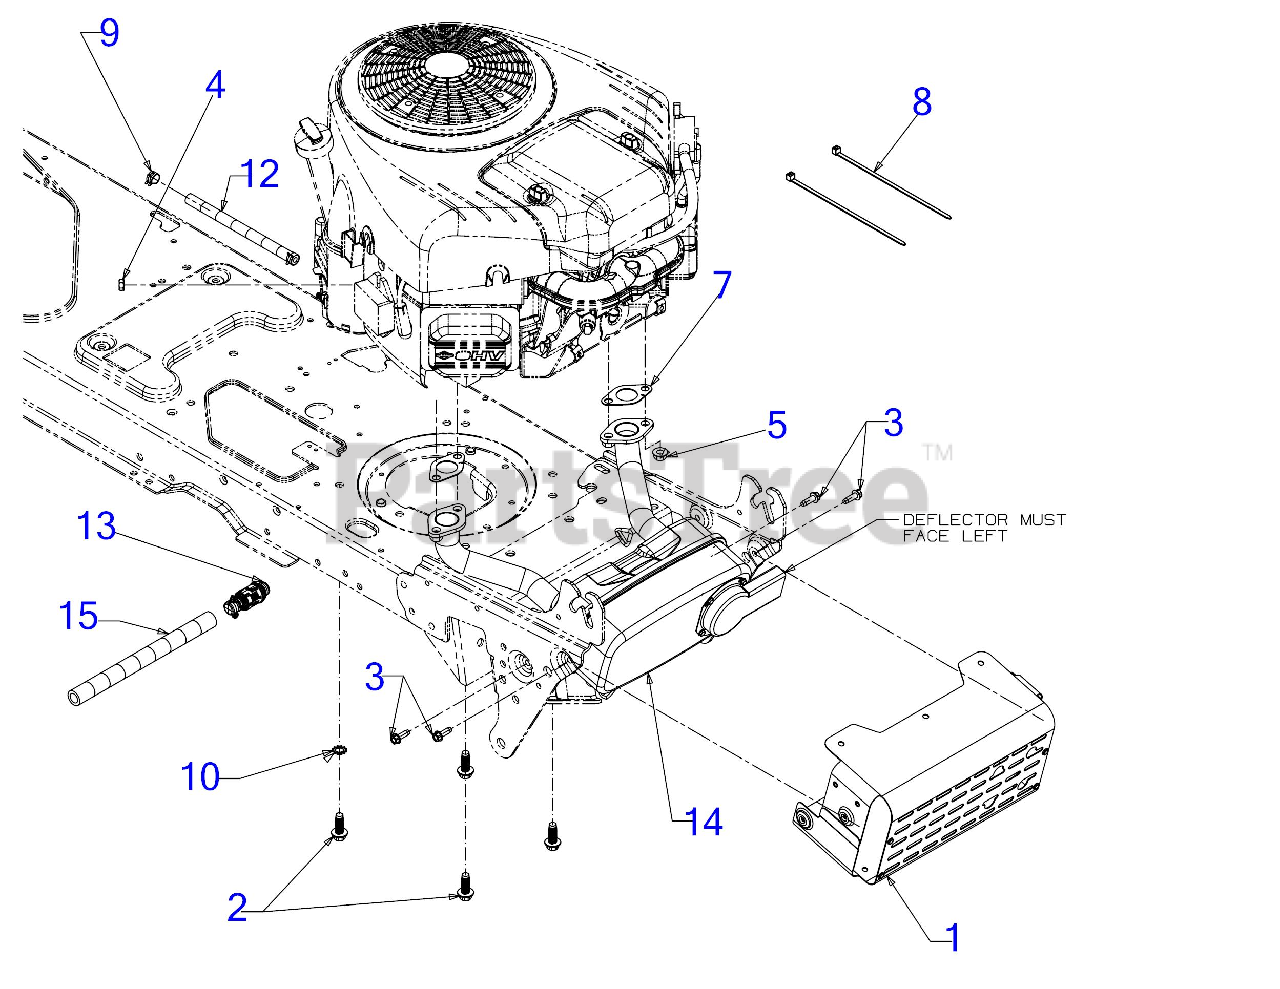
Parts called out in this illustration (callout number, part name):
2	SCREW 3/8-16 x 1
3	SCREW 1/4-20 x .750
4	SEMS NUT 1/4-20
5	HEX FLANGE NUT M8X
7	MUFFLER GASKET
8	7" CABLE TIE
9	HOSE CLAMP 1/20
10	LOCK WASHER 3/8
12	FUEL HOSE LOW PERMEATION
13	OIL DRAIN VALVE
14	MUFFLER
15	DRAIN HOSE 14''
